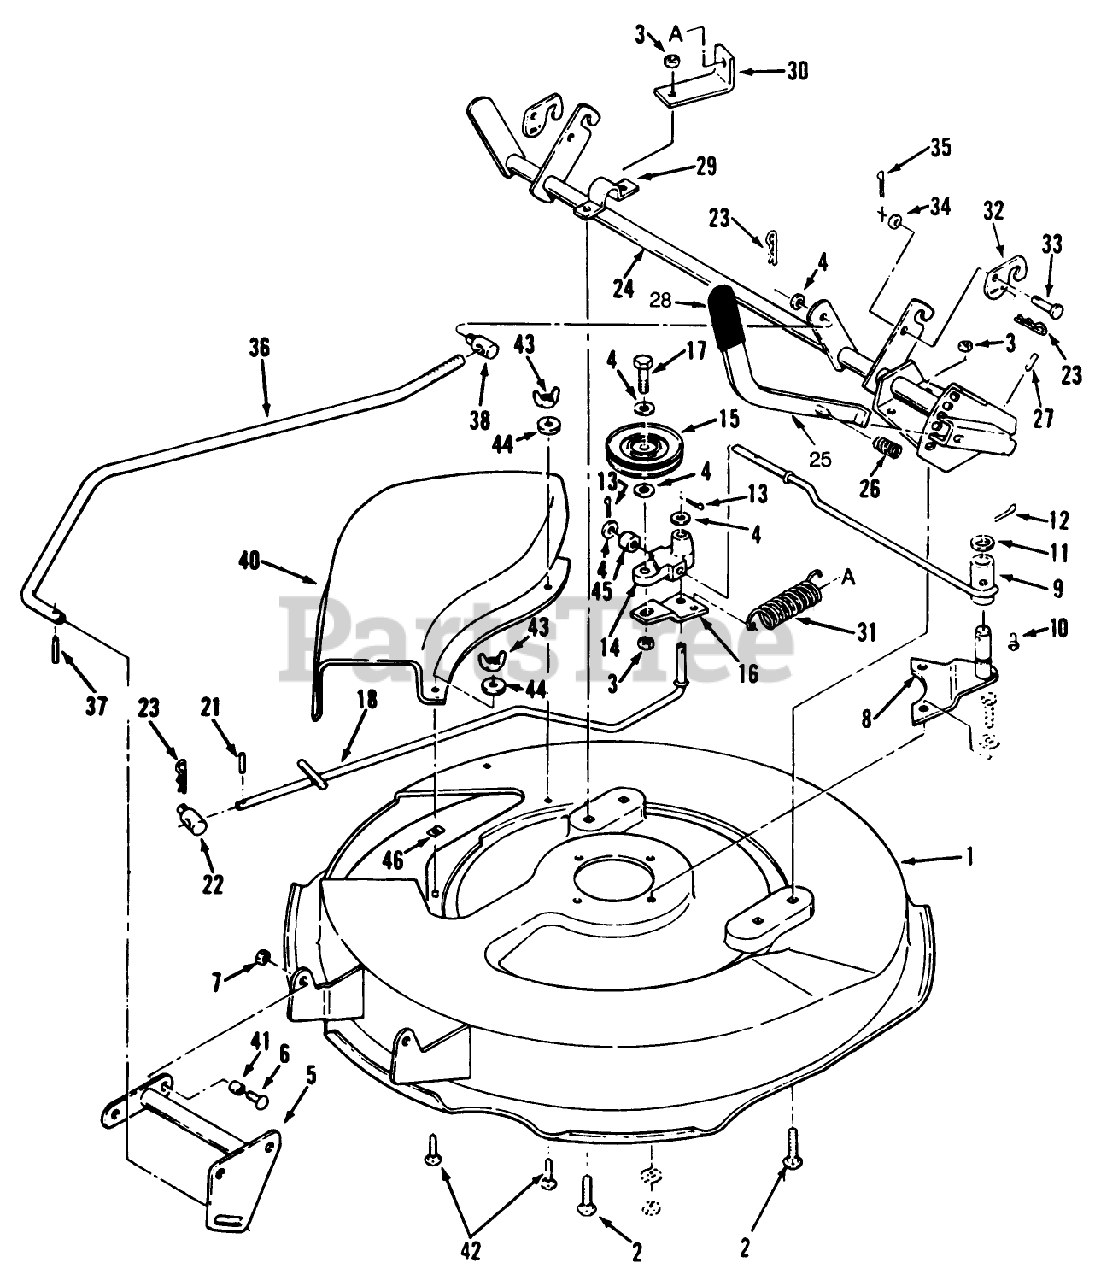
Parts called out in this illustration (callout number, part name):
5	ASM-FRONT LIFT *R
11	WASHER
14	BLOCK IDLER
15	PULLEY-IDLER V
22	TRUNNION-LIFT
23	Hairpin Cotter
26	SPRING-COMPRESSION
27	PIN-SPIROL
29	CLAMP
31	SPRING-EXTENSION
36	ASS'Y-HEIGHT ADJ *R
37	SPIROL PIN
38	STUD-TRUNION
41	SPACER
44	WASHER
45	SPACER
46	SPEED NUT
